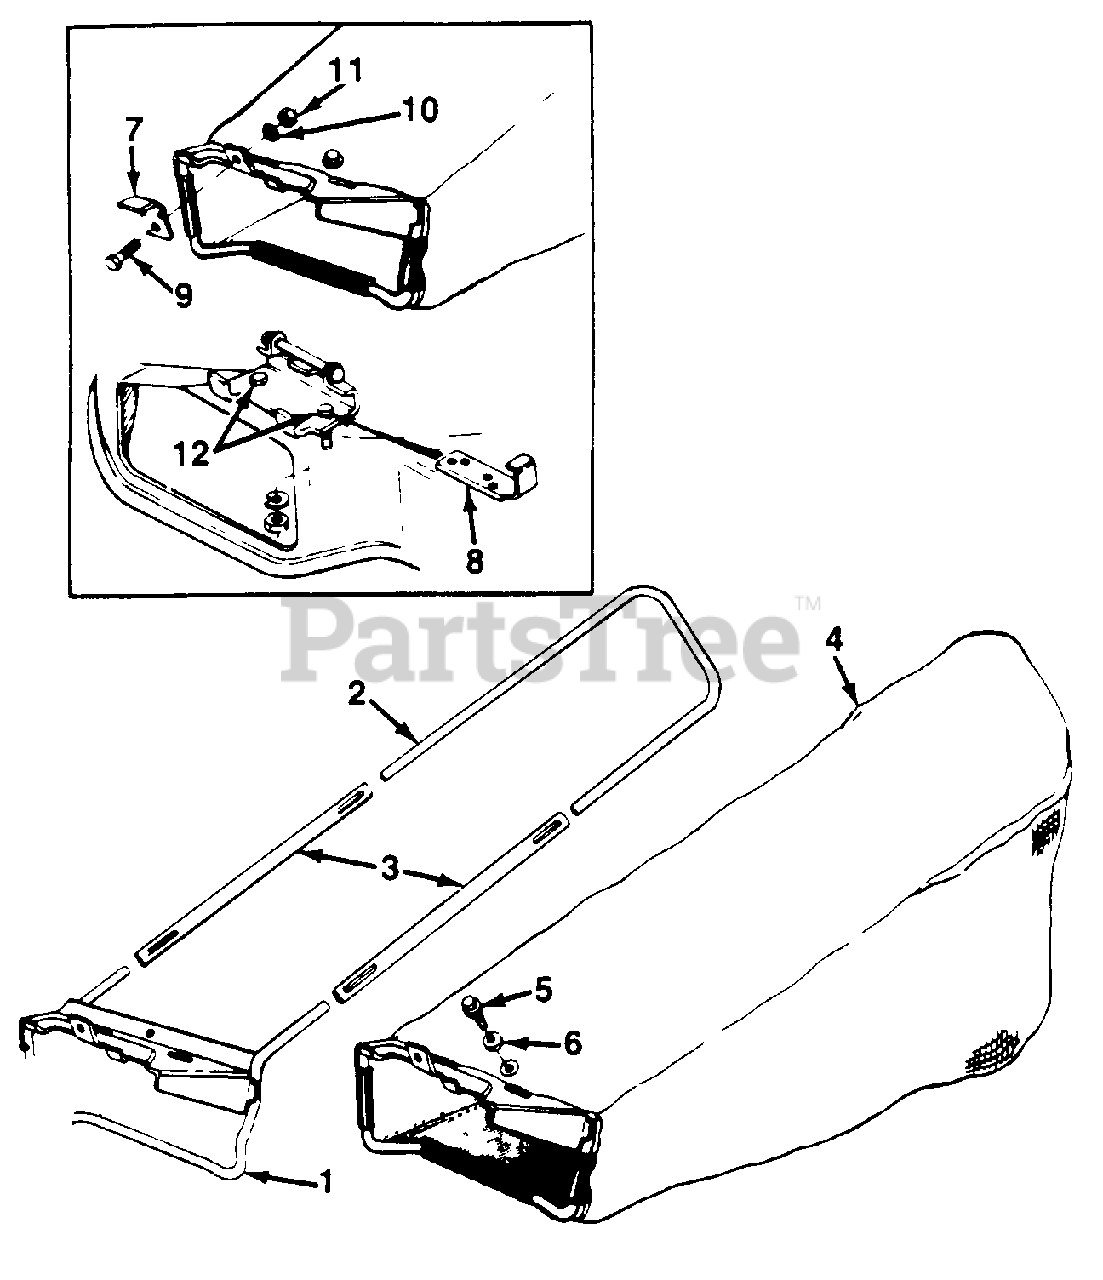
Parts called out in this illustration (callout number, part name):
4	Grass Bag
5	Hex Wash Hd. TT-Tap Scr. 1/4-20 x 5" Lg.
6	Bell-Wash. 1/4" I.D.
7	Deflector Stop
8	Support Plate
9	Hex Bolt 1/4-20 x .5" Lg.
10	L-Wash. 1/4" I.D.
11	Hex Nut 1/4-20 Thd.
12	Hex Bolt 1/4-20 x .62" Lg.
